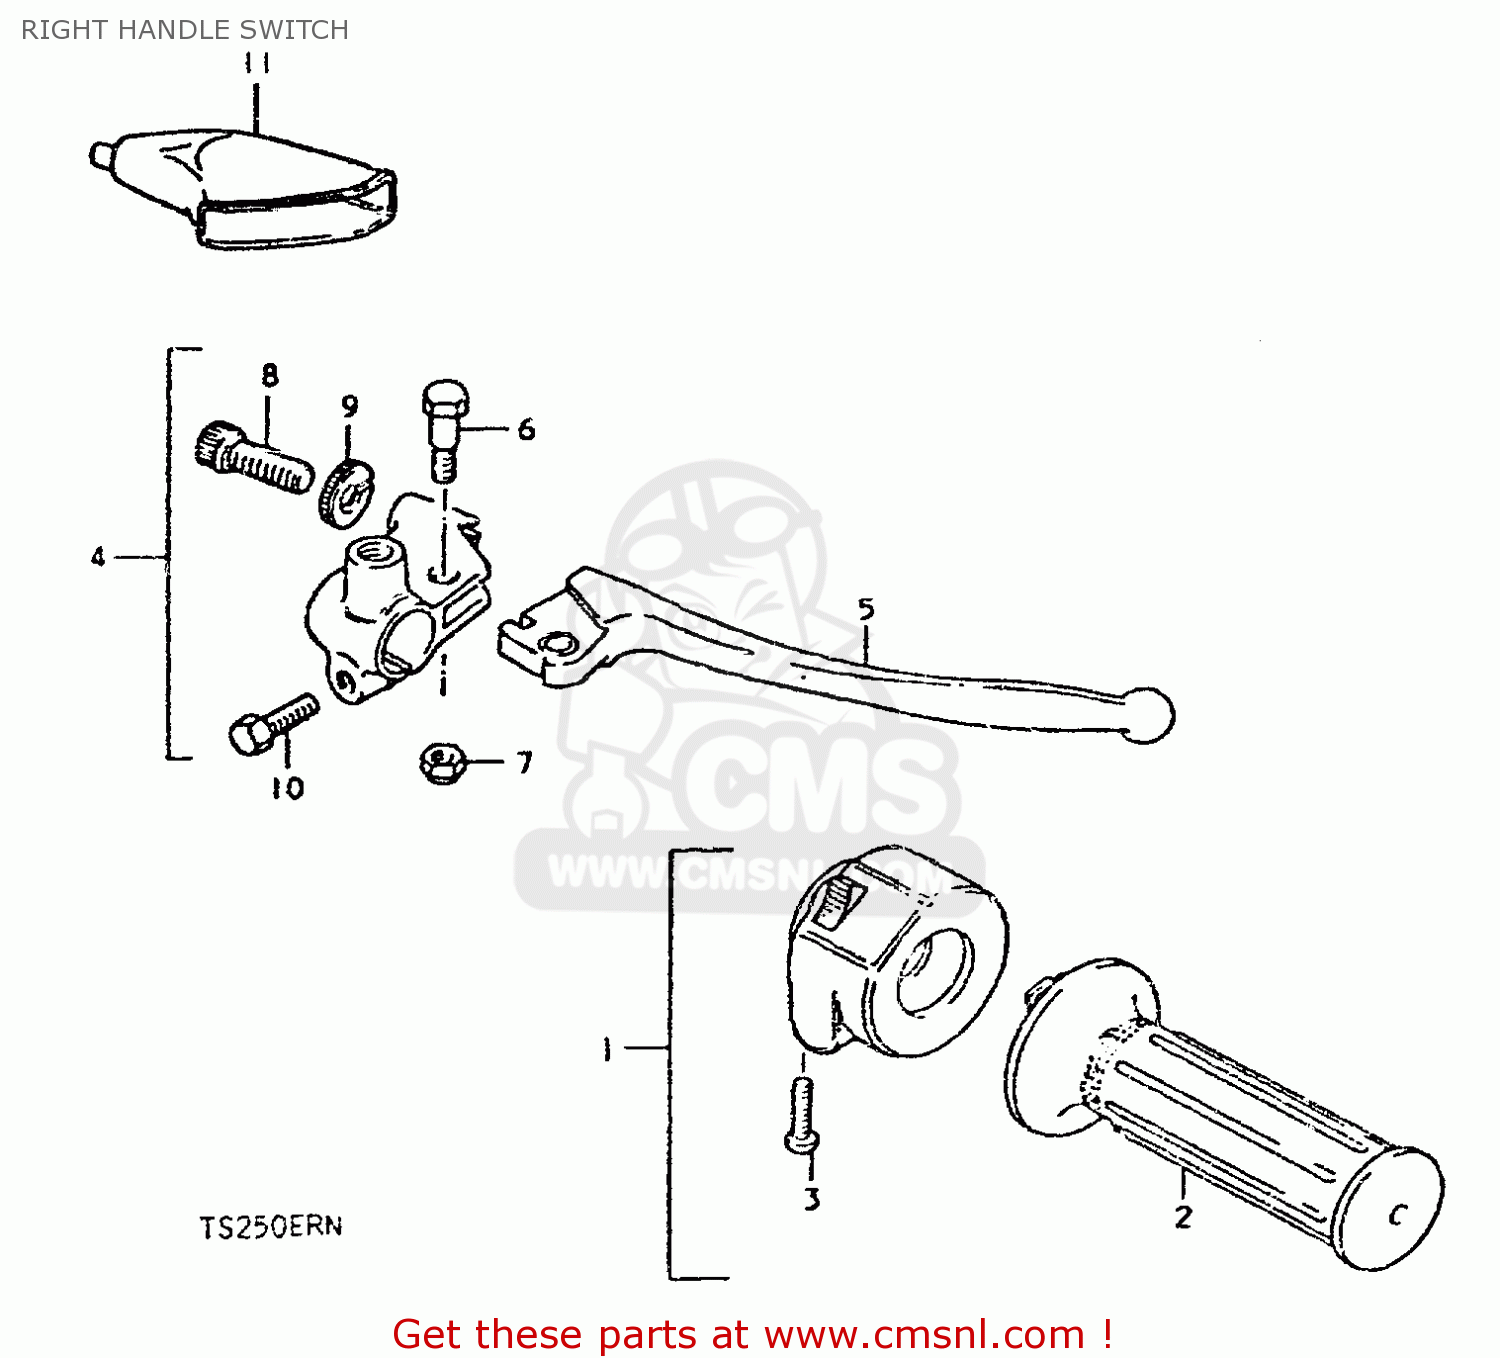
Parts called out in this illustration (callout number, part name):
1	CASE ASSEMBLY,THROTTLE
2	GRIP,THROTTLE
3	SCREW
4	LEVER ASSY, BRAKE
5	LEVER,BRAKE
6	BOLT,LEVER
7	NUT 6MM
8	ADJUSTER,CABLE
9	NUT,CABLE ADJUSTER
10	BOLT
11	COVER,CLUTCH LEVER
